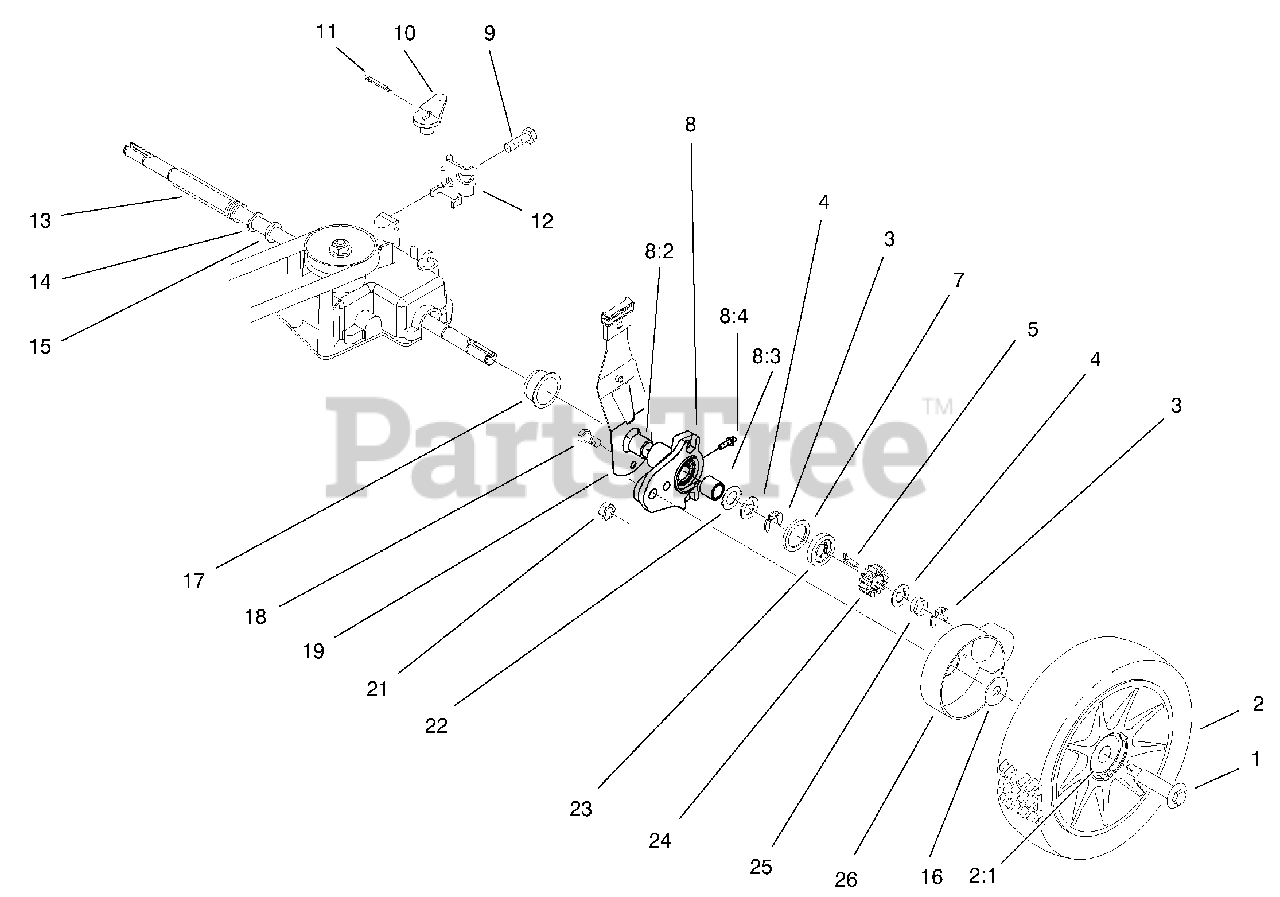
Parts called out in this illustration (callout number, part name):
1	Bolt-Shoulder
2	Wheel & Tire ASM
3	Ring-Retaining
4	Washer-Thrust
5	Key-Rocking LH
7	Ring-Friction
8	Arm ASM-Rear Height
8:4	Fitting-Grease
10	Lever-Shift
11	Pin-Cotter
12	Retainer-Cable
13	Cover-Drive Shaft
15	Washer-Flat
16	Washer-Stepped
19	Rear Spring Arm
21	Nut-Lock
22	Washer-Arm, Pivot
24	Gear-Pinion
25	Spring-Compression
26	Cover-Wheel
